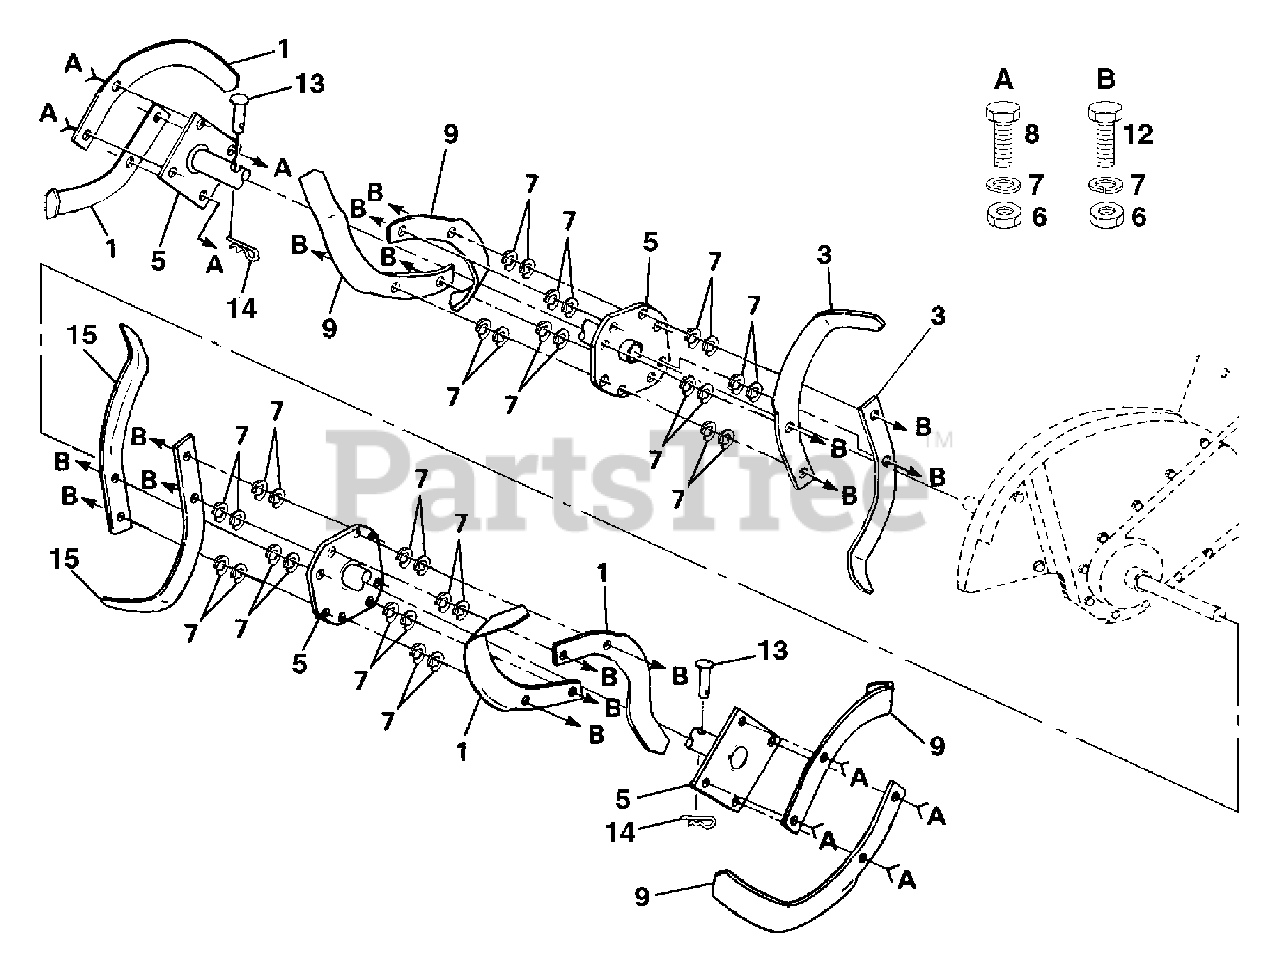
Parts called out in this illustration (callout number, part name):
1	Tine, L.H., 14"
3	Tine, L.H., 14"
5	Hub Assembly
6	Nut, Hex 3/8-24
7	Washer, Lock 3/8
8	Bolt, Hex Head 3/8-24 x 1
9	Tine, R.H., 14"
12	Bolt, Hex Head 3/8-24 x 1-1/2
13	Rivet, Panhead
14	Clip, Hairpin
15	Tine, R.H., 14"
